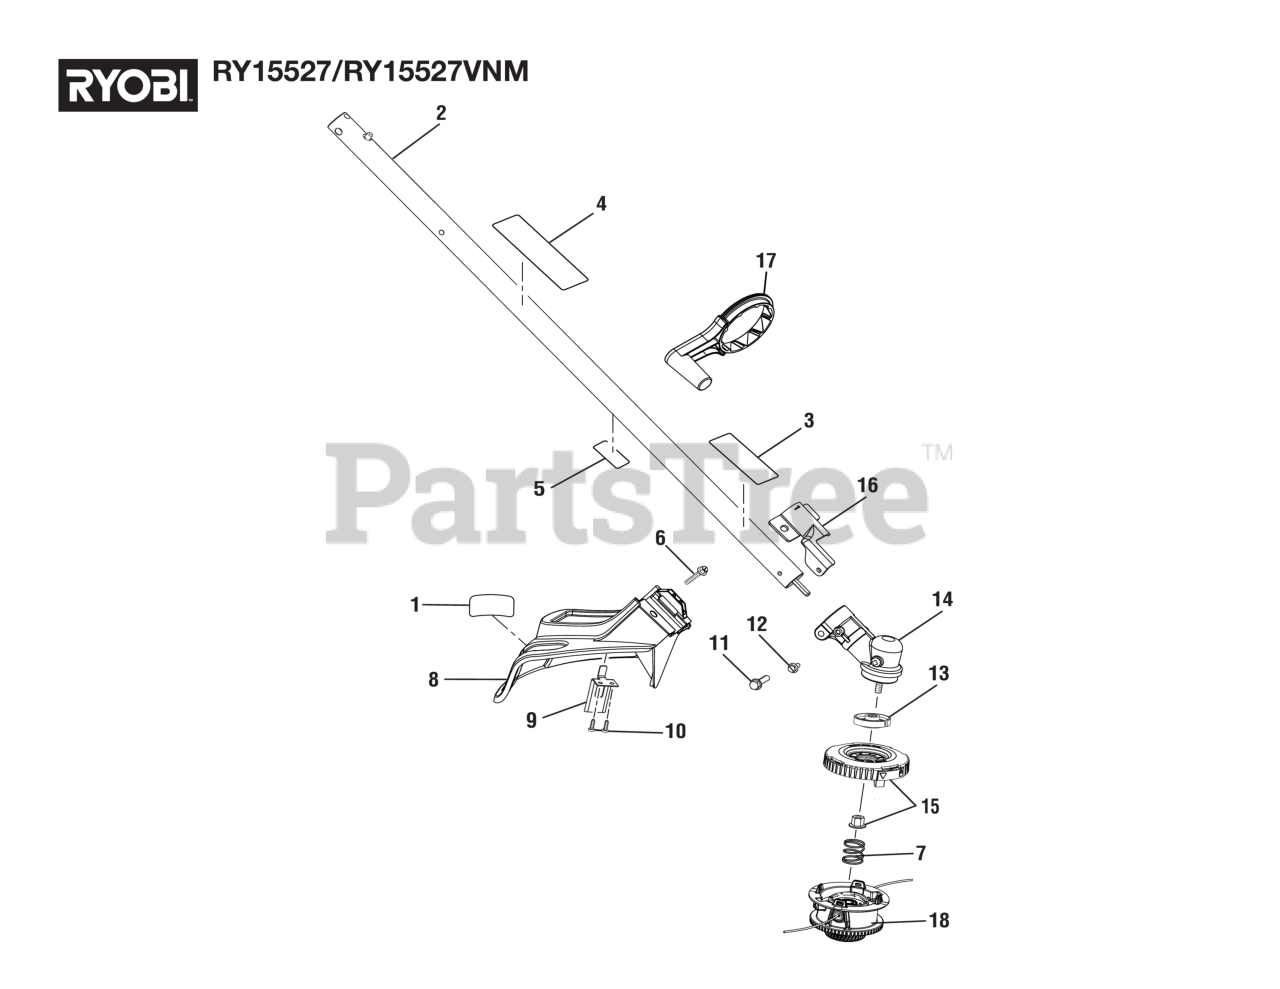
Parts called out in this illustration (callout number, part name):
1	Max. Run Time/Performance Label
2	Straight Shaft Assembly (Inc. Key Nos. 3-5)
3	Icon Warning Label
4	Ryobi EXPAND-IT Label
5	Data Label
6	SCREW (#1/4-20 X 1-1/4 in. HEX WASHER HD.)
7	Compression Spring
8	Grass Deflector Assembly
9	Line Cut-off Blade
11	Screw (1/4-20 x 1-1/4 in., Hex Washer Hd. S.T.)
12	Screw w/Washer (10-24 x 5/8 in., Hex Hd. T.F.)
13	FLANGED WASHER
14	Gear Case Assembly
15	Bump Feed Trimmer Head Assembly (Inc. Key No. 21)
16	GRASS DEFLECTOR CLAMP
17	Crank Handle
